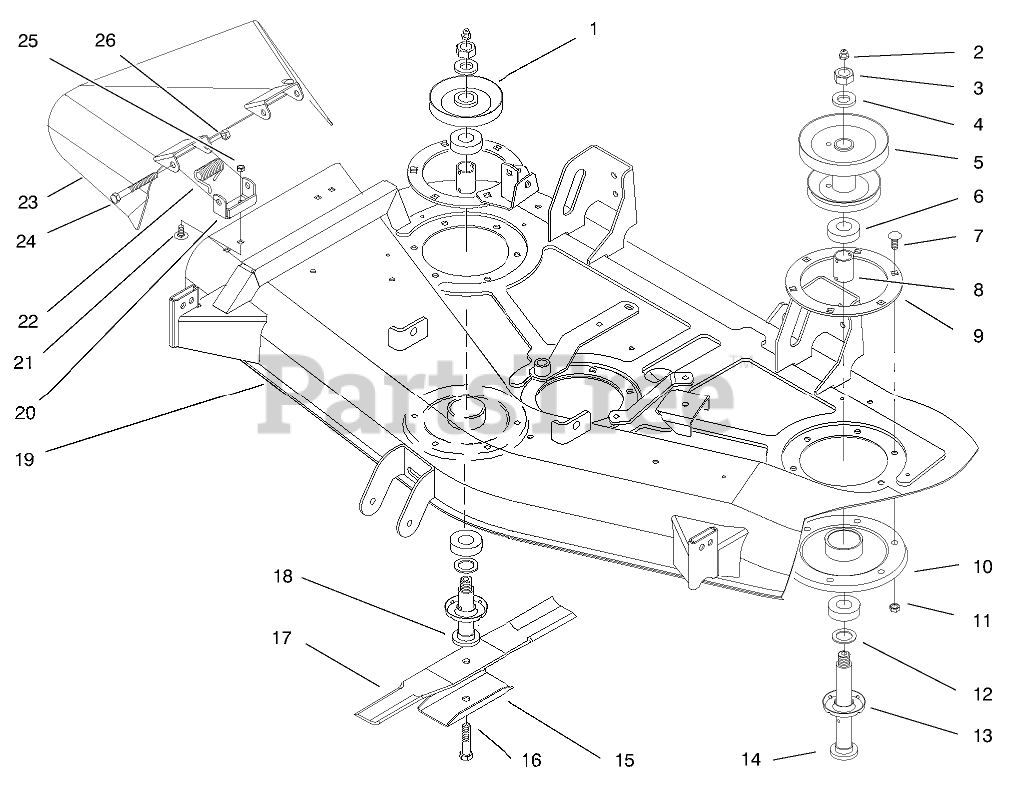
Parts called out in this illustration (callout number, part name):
1	PULLEY
2	FITTING-GREASE
3	NUT-JAM
4	WASHER-FLAT
5	PULLEY-DOUBLE
6	BEARING-BALL
7	SCREW-CARR
8	SPACER-BEARING
9	RING-DECK SUPPORT
10	HOUSING-SPINDLE
11	NUT-HF
12	WASHER-BACKUP
13	SHIELD-BEARING
14	SHAFT - SPINDLE
15	STIFFENER-BLADE
16	SCREW-BLADE
17	Blade (Only On: 78280)
17	Blade (Only On: 78285)
18	SHAFT-SPINDLE
19	DECK ASM
20	BRACKET-PIVOT
21	SCREW-CARR
22	SPRING
23	Deflector ASM
24	SCREW-HH
25	NUT-LOCK, NI
26	NUT-HEX
